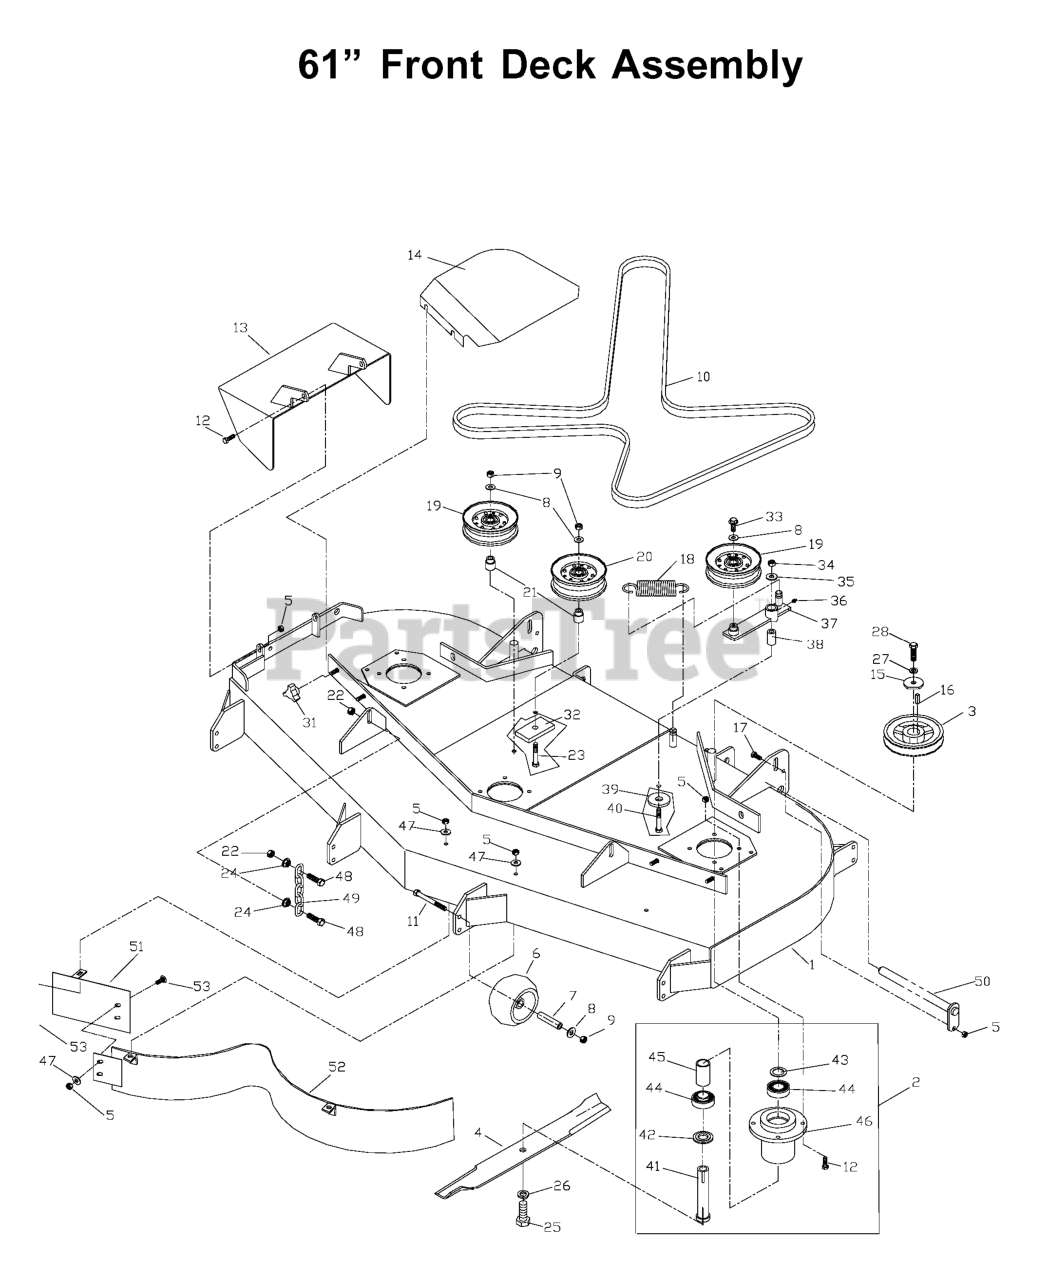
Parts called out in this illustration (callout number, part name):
1	DECK W/DECALS 61" HUS
2	HOUSING ASM.
4	BLADE OEM 21" (61" DECK)
5	NUT 5/16C CENTERLOCK
6	ANTI-SCALP ROLLER
8	WASHER 3/8 FLAT
9	NUT 3/8C CENTERBLOCK
10	DECK BELT 61
11	HCS 3/8C X 3 1/2
12	HCS 5/16C X 1
13	DISCHARGE CHUTE
14	61 B.S.PAINTED, RT
15	SPINDLE WASHER
16	KEY 1/4 SQ X 1 1/8
17	HCS 5/16C X 3/4
18	DECK SPRING
19	IDLER PULLEY
20	IDLER PULLEY (TALL)
21	IDLER BUSHING
22	NUT 7/16C CENTERLOCK
23	HCS 3/8C X 2 1/2
24	NUT 7/16C WHIZ
25	HCS 5/8F X 1 1/4
26	LOCKWASHER 5/8
27	WASHER 7/16 LOCK
28	HCS 7/16F X 1 1/2
31	KNOB, THREE PRONG
32	SUPPORT PLATE
33	4CS 3/8C X 1 SERRATED HEAD
34	NUT 1/2-13 HEX NYLOC ZD
35	WASHER 1/2 FLAT
36	ZERK
38	PIVOT BUSHING
39	WASHER, SUPPORT
40	HCS 1/2C X 3 1/4
42	MACHINERY BUSHING 10 GA.
43	BUSHING.MACHINE.18.GAUGE
44	BEARING
46	HOUSING, DIE CAST
47	WASHER 5/16 FLAT
48	HCS 7/16C X 1 1/2
49	LIFT CHAIN
51	CENTER BAFFLE - 61
52	MAIN BAFFLE - 61" BLK
53	CARRIAGE BOLT 5/16C X 5/8"
539105103	61 B.S.PAINTED, LT ORANGE
